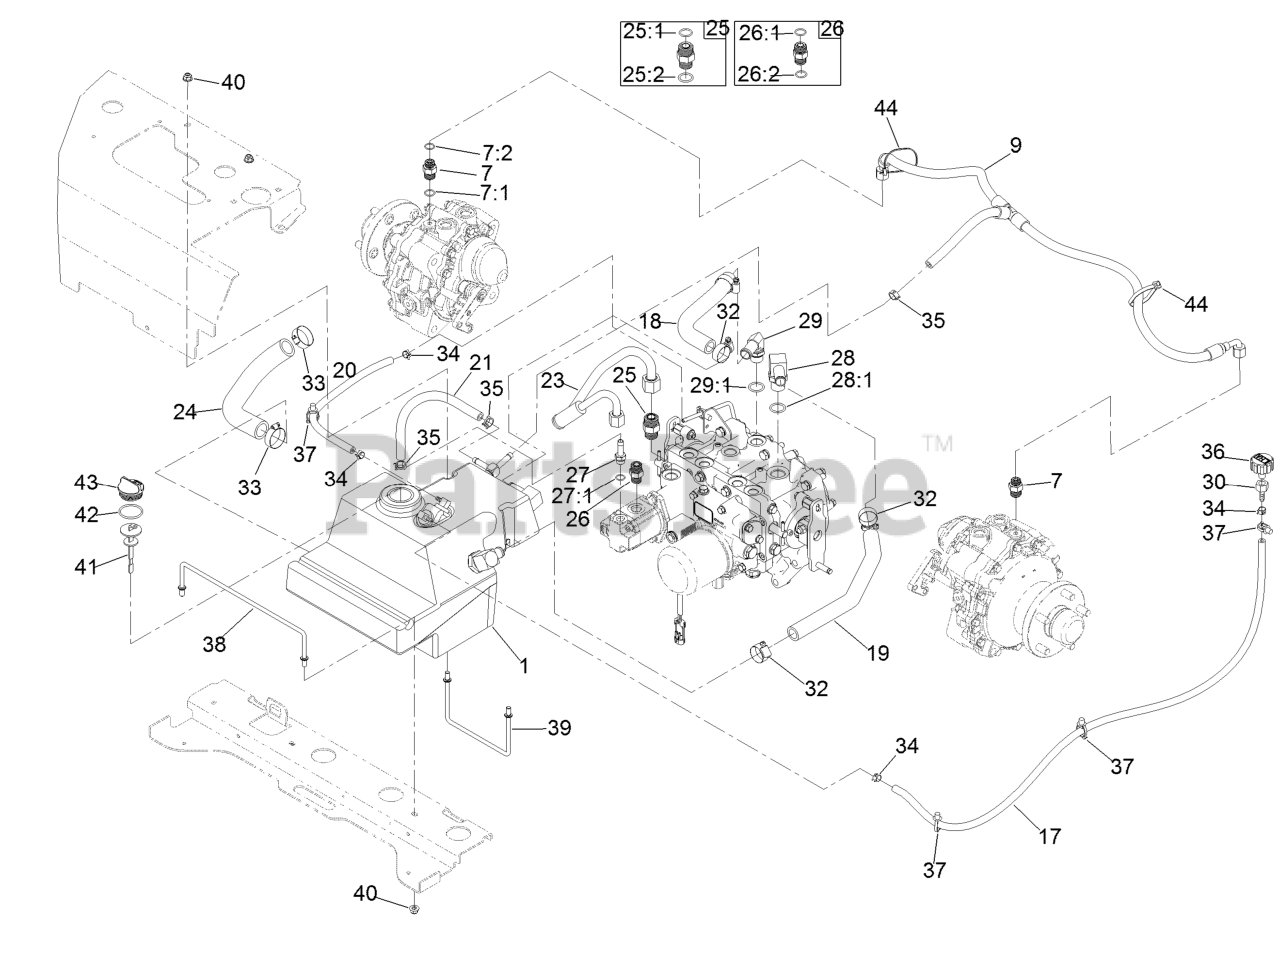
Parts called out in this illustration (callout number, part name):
1	HYD Reservoir ASM
7	Fitting-Straight
7:1	O-Ring
7:2	O-Ring
9	Tee Hose ASM
18	Hose-Return
19	Hose-Return
23	Tube ASM
24	Hose-Suction
25	Fitting-Straight
25:1	O-Ring
25:2	O-Ring
26	Fitting-STR
26:1	O-Ring
26:2	O-Ring
27	Adapter-Straight
27:1	O-Ring
28	Fitting-Elbow, 90
28:1	O-Ring
29	Fitting-90
29:1	O-Ring
30	Fitting-Straight
32	Clamp-Hose
33	Clamp-Hose
34	Clamp-Hose
35	Clamp-Hose 11/16
36	Breather
37	Clip-Tie
38	Rod-Support, HYD Tank
39	Rod-Support, HYD Tank
40	Nut-Nyloc 5/16-18 Flg
41	Dipstick
43	Plug-Plastic
44	Tie-Cable 7 15/16 (Large)
